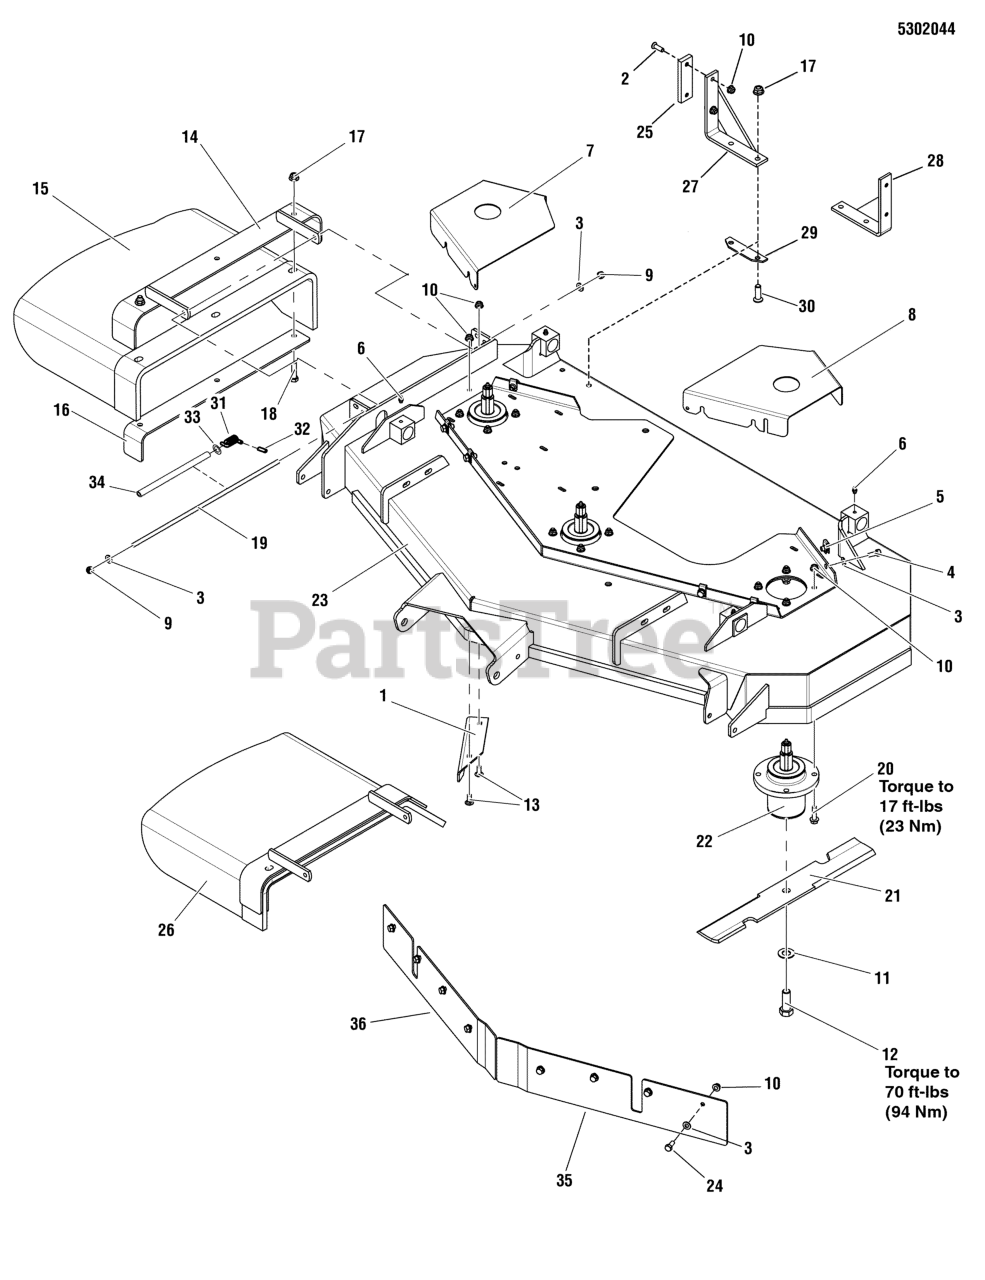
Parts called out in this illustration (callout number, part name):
1	PLATE, DEFLECTOR - BLK
2	SCREW, 5/16-18 X 1, PHILLIPS HD, BZ
3	WASHER, 5/16" SAE
4	BOLT, 5/16-18 X 1 GD5 YZ
5	BODY CLIP, 5/16-18-7GA MATERIAL
6	GREASE FITTING, 1/4-28 STRAIGHT
7	GUARD, DECK, 52, RH, SW20 - RED
8	GUARD, DECK, 52, LH, SW20 - RED
9	NUT, 5/16-24 HEX NYLON LOCK
10	NUT, 5/16-18 HEX NYLOCK FLANGE
11	WASHER, 5/8 GRADE 8, YZ
12	BOLT, 5/8-11 X 1-3/4 GD8
13	BOLT, 5/16-18 X 3/4, CARRIAGE
14	WELD, MOUNT, DISCHARGE CHUTE - BLK
15	CHUTE, DISCHARGE, BEND RUBBER 52"
16	SUPPORT,DISCHARGE CHUTE - BLK
17	NUT, 3/8-16 HEX NYLOCK FLANGE
18	BOLT, 3/8-16 X 1-1/2" GD5 CZ
19	ROD, 5/16 X 13.75, TBE
20	BOLT, 5/16-18 X 1 1/4 FLANGE
21	BLADE, SET OF THREE (INCLUDES 3 BLADES)
22	ASSM, SPINDLE, LOW PROFILE
23	DECK SHELL W/ DECALS, 52, SW30SDCE
24	BOLT, 5/16-18 X 3/4 GD5
25	PAD, FRICTION, .375 X 1.25 X 4.00
26	KIT, DISCHARGE CHUTE, 44/48/52
27	WELD, FRICTION PAD HOLDER, RH - RED
28	WELD, FRICTION PAD HOLDER, LH - RED
29	PLATE, BRACKET SUPPORT - RED
30	BOLT, Carriage, 3/8-16 X 1
31	SPRING, TORSION
32	CAP, PROTECTOR, .120 ID
33	WASHER, 5/16 FENDER
34	SPACER, TORSION SPRING, 9.63 LG
35	BAFFLE, FRONT DISCHARGE, LH, 52RD SW30 - RED
36	BAFFLE, FRONT DISCHARGE, RH, 52RD SW30 - RED
